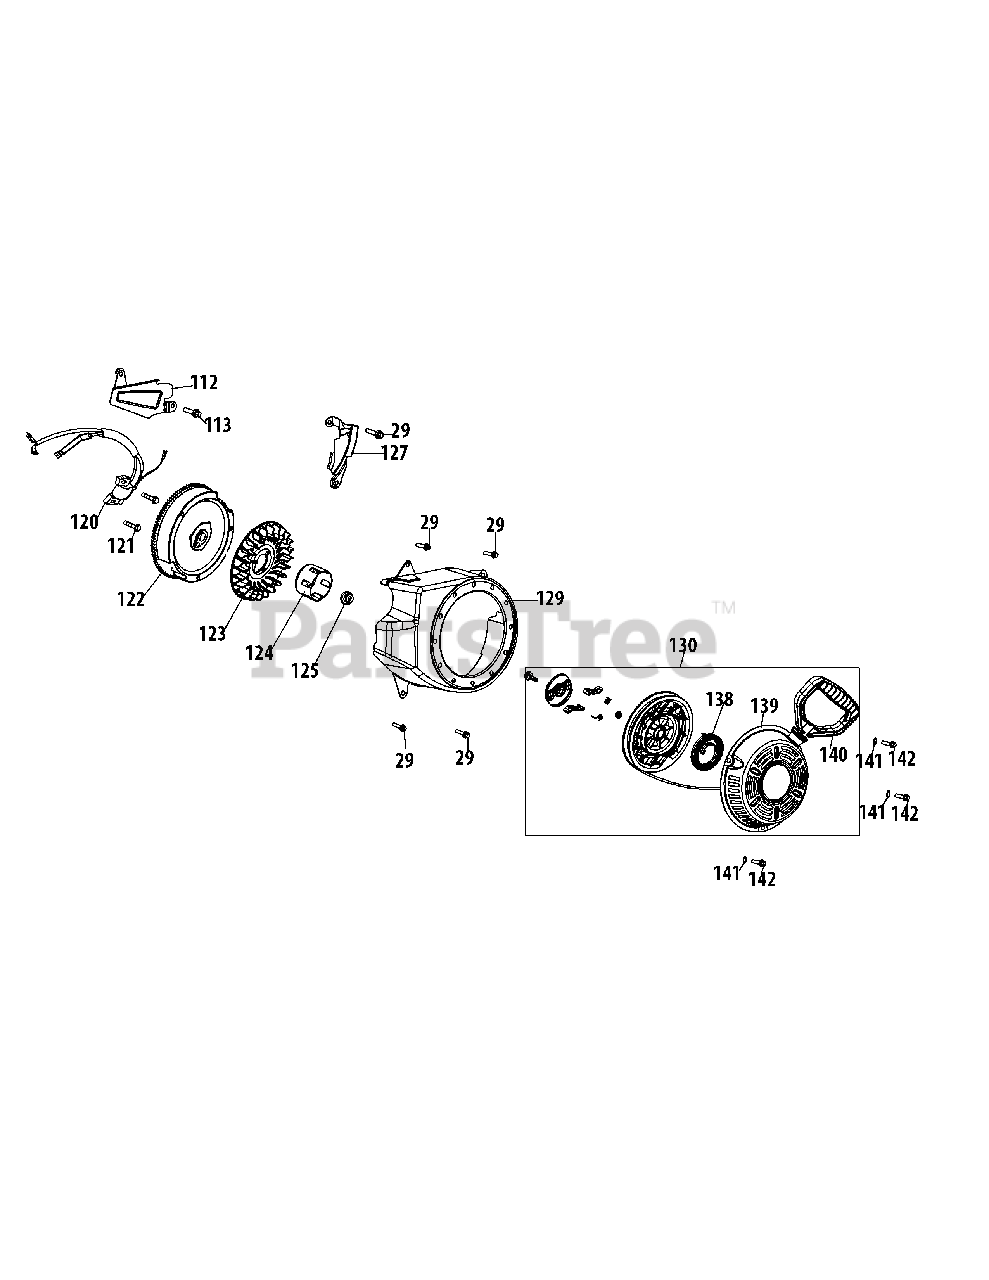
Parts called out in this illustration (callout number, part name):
29	Bolt M6×12
113	Bolt M6×10
120	Ignition Module
121	Bolt M6×25
122	Flywheel
123	Cooling Fan
124	Starter Cup
125	Flange Nut M14×1.5
127	Lower Shield
129	Blower Housing
130	Recoil Starter
138	Recoil Spring
139	Blower Housing
140	Starter Handle
141	Washer 6
142	Bolt M6×10
